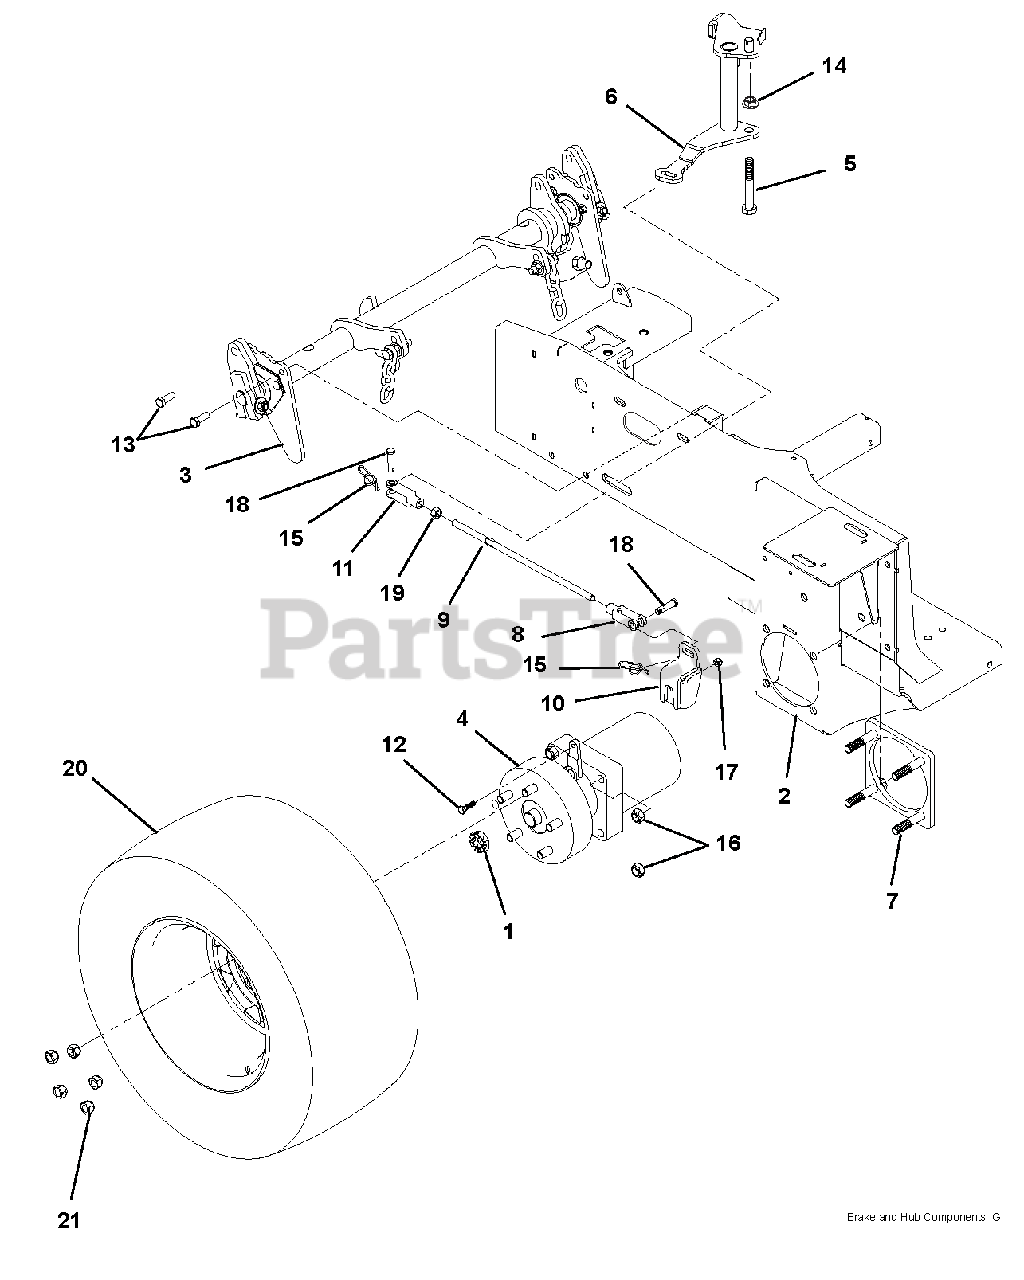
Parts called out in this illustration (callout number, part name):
1	NUT, 1-20 SPECIAL CASTLE S/O
2	FRAME WITH DECALS ACM
3	Rear Lift Rod Assembly
4	MOTOR, LH HYDRO GEAR WHEEL
4	MOTOR, LH WHEEL
4	MOTOR, RH HYDRO GEAR WHEEL
4	MOTOR, RH WHEEL
5	BRG, FLG .502X.629X.421
6	WLDT, LH PARK BRAKE CONTROL
6	WLDT, RH PARK BRAKE CONTROL
7	WLDT, WHEEL MOTOR PLATE
8	YOKE, 3/8-24 LH ADJUSTABLE
9	ROD, STRAIGHT PARK BRAKE CONTR
10	WLDT, BRAKE ARM EXT. PARKER
11	YOKE, 3/8-24 RH ADJUSTABLE
12	@BLT-HEX .25-20X1.00 GR5 YWZC
13	@BLT-HEX .38-16X1.00 GR5 YWZC
14	@BLT-HEX .50-13X2.75 GR5 YWZC
15	RING, RUE .375 X .054 X 1.254
16	@NUT-HEX .50-13 YWZC
17	@NUT-LK-NYL .250-20 YWZC
18	PIN-CLEV .375X1.38X1.14 YWZC
19	NUT-HEX .375-24 YWZC
20	TIRE/WHEEL ASSY, 24X11.50-12
20	TIRE/WHEEL ASSY, 24X12-12
20	TIRE, 24X11.50-12
20	RIM, 12X8.5
21	NUT, 1/2-20 LUG, GRADE 5
